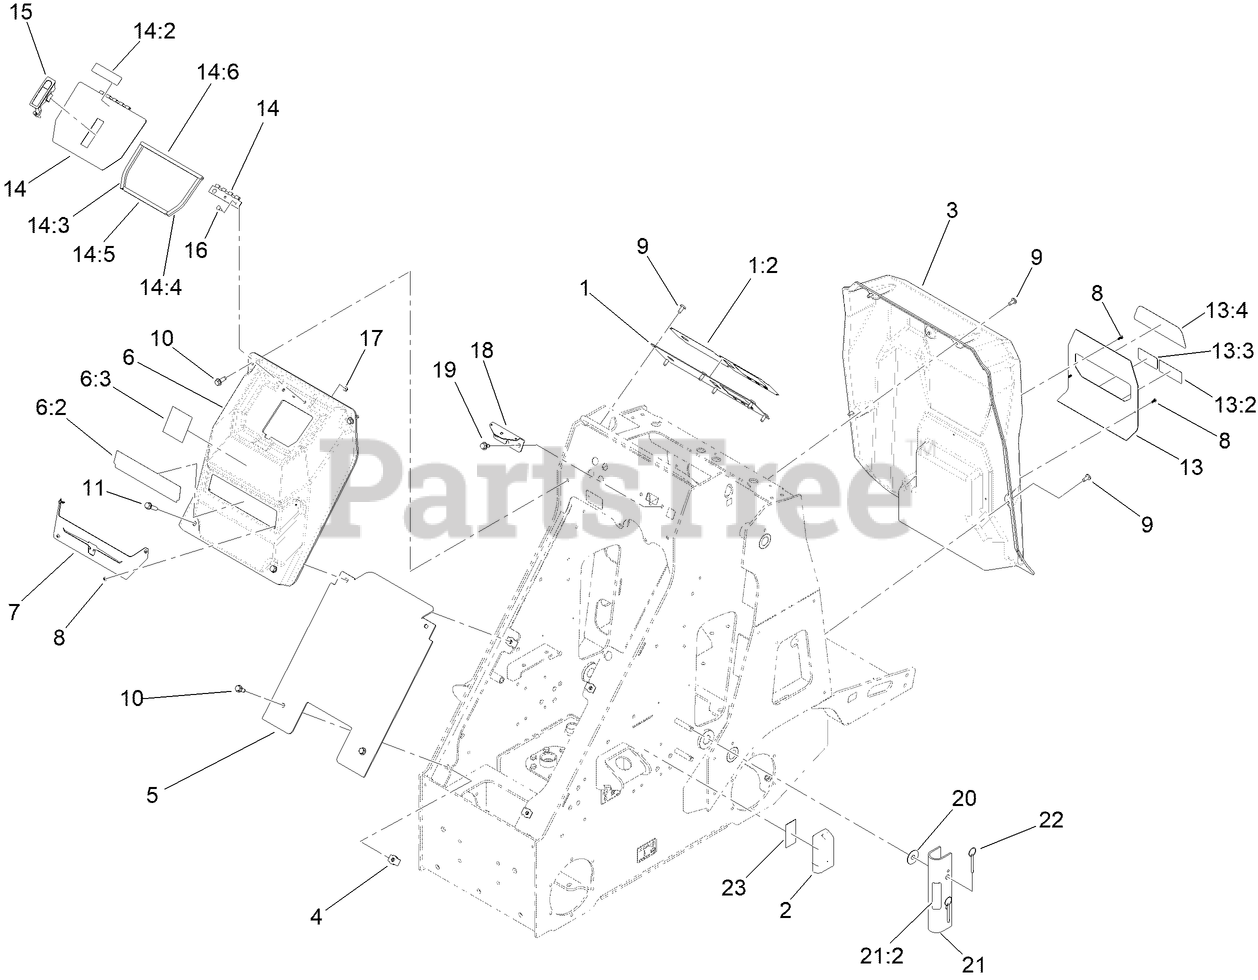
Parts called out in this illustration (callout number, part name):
1	PANEL-INSTRUMENT [SUNBELT]
1:2	DECAL - CONTROLS
2	GPS-WIRELESS
3	HOOD ASM, REAR [SUNBELT]
4	NUT-TINNERMAN
5	COVER-FRONT,LOWER
6	HOOD ASM, FRONT [SUNBELT]
6:2	DECAL - BACKER, RED
6:3	DECAL-RSRVS3X3-LX
7	PLATE-HOOD
8	SCREW-PLASTITE, TORX PAN
10	SCREW-HWH
11	SCREW-HWH
13	PLATE - CORD [SUNBELT]
13:2	DECAL - CHARGING PORT
13:3	DECAL-BATTERY CHARGER
13:4	DECAL-HYPERCELL
14	DOOR - ACCESS
14:2	DECAL-SERVICE, SHUT-OFF
14:3	FOAM - DOOR, RH
14:4	FOAM - DOOR, LH
14:5	FOAM - DOOR, BOTTOM
14:6	FOAM - DOOR, TOP
15	LATCH - COMPRESSION
16	BOLT-CARR
17	NUT-HF
18	BRACKET - LIGHT
19	SCREW-HWH
20	WASHER-PLASTIC
21	LOCK CYLINDER ASM
21:2	DECAL - CYLINDER LOCK
22	PIN-COTTERLESS
23	ADHESIVE
